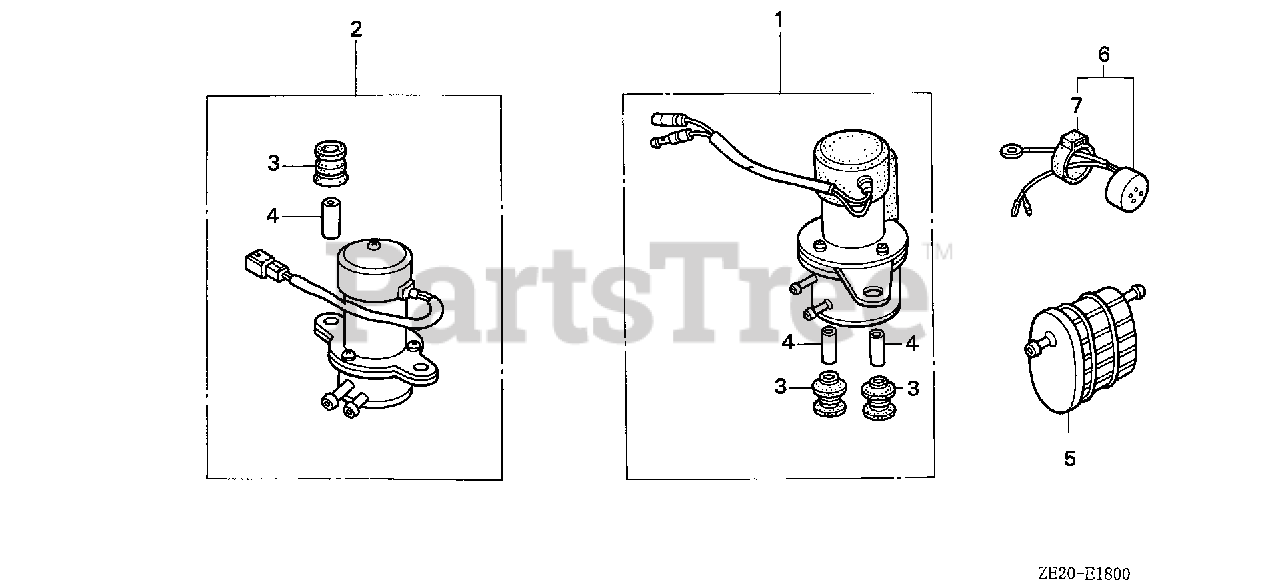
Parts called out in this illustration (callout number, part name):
1	PUMP ASSY., FUEL (ELECTROMAGNETIC) (MSDS)
1	PUMP ASSY., FUEL (MITSUBISHI) (NOT AVAILABLE)
2	PUMP ASSY., FUEL (ELECTROMAGNETIC) (MSDS)
3	RUBBER, FUEL PUMP MOUNTING
4	COLLAR, DISTANCE
4	COLLAR, FUEL PUMP DISTANCE
5	FILTER, FUEL
6	BUZZER ASSY.
7	SUSPENSION, AUDIBLE PILOT
